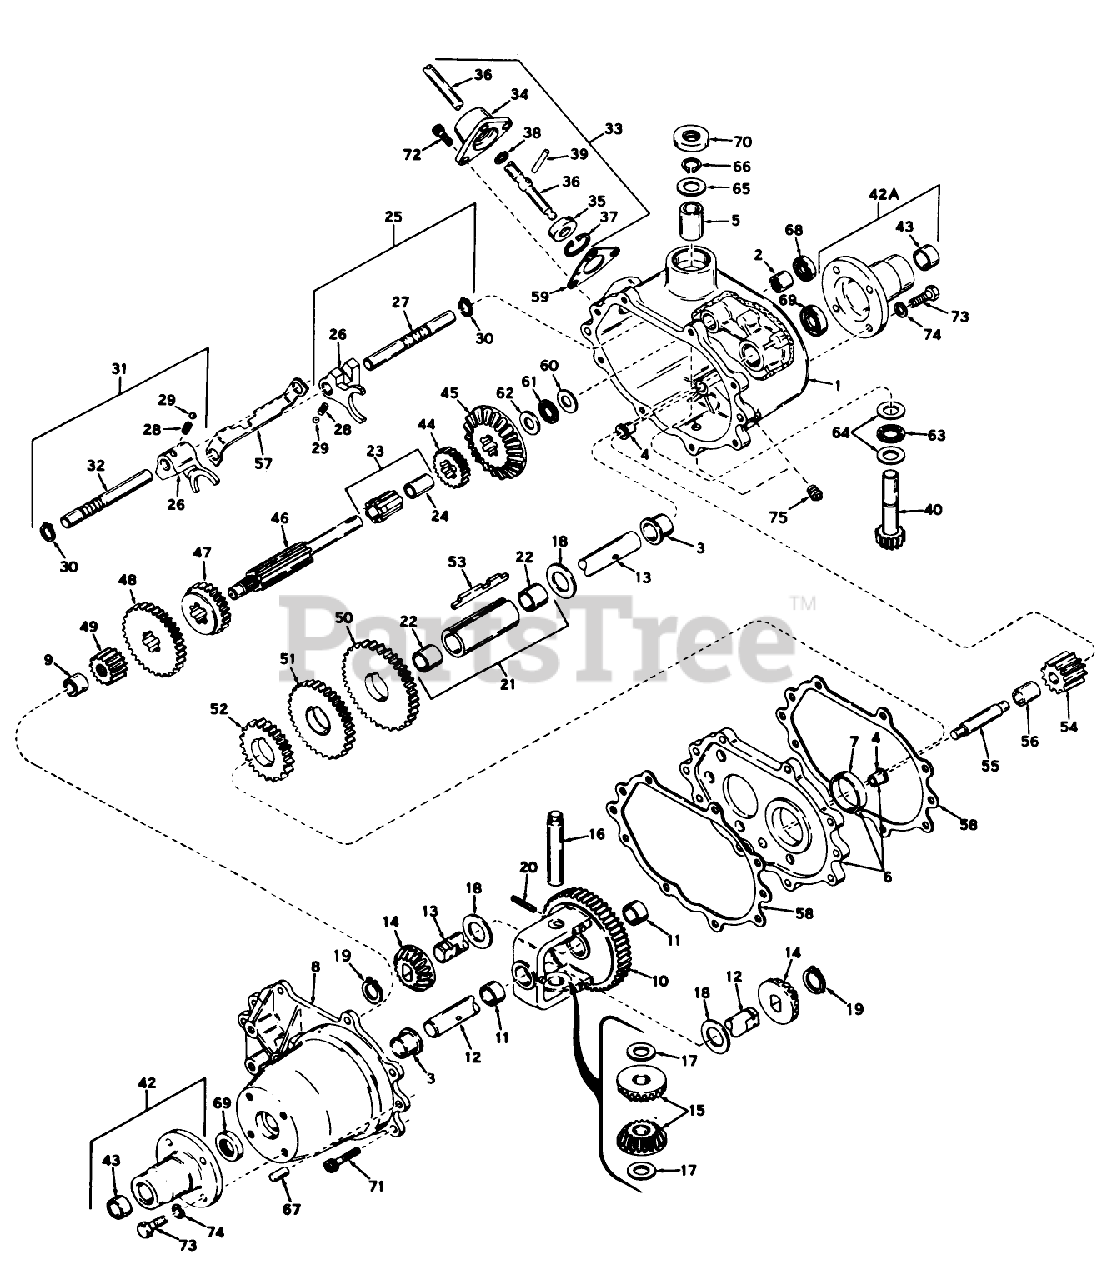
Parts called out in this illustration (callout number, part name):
1	Transaxle Case Assy (Incl. Nos. 2 thru 5)
2	Needle Bearing
3	Bronze Bearing
4	Bronze Bearing
5	Bronze Bearing
6	Plate Assy., Center (Incl. Nos. 4 7)
7	Bronze Bearing
8	Cover Assy., Transaxle (Incl.Nos. 3 9)
9	Needle Bearing
10	Gear Assy., Differential (Incl. No. 11)
11	Bushing
12	Left Hand Axle
13	Right Hand Axle
14	Bevel Gear
15	Gear Pinion
16	Drive Pin
17	Thrust Washer
18	Washer
19	Snap Ring
20	Roll Pin
21	Countershaft Sleeve Assy (Incl. No. 22)
22	Bronze Bearing
23	Idler Shaft Assy (Incl. No. 24)
24	Bronze Bearing
25	Shift Rod Assy (1st and Rev.)(Incl. Nos. 26 thru 30)
26	Shift Fork
27	Shift Rod
28	Spring
30	Ring-Snap
31	Shift Rod Assy (2nd 3rd)(Incl. No. 26, 28, 29, 30, and 32)
32	Shift Rod
33	Shift Lever and Housing Assy (Incl. Nos. 34 thru 39)
34	Shift Lever Housing
35	Keeper-Shift Lever
36	Shift Lever
37	Ring-Snap
38	O Ring
39	Roll Pin
40	Input Shaft
41	Input Pinion
42	No. 43)
42A	Housing Assy Axle (Incl. No. 43)
43	Bronze Bearing
44	Gear (10 teeth)
45	Bevel Gear (33 teeth)
46	Shifter and Brake Shaft
47	Gear, Shifting (2nd 3rd)
48	Gear, Shifting (1st Rev.)
49	Spur Gear (12 teeth)
50	Countershaft Drive Gear (39 teeth)
51	Gear (34 teeth)
52	Countershaft Gear (25 teeth)
53	Countershaft Key
54	Reverse Idler
55	Reverse Idler Shaft
56	Reverse Idler Spacer
57	Shifter Stop
58	Gasket, Case Cover
59	Shift Lever Housing Gasket
60	Thrust Washer
61	Thrust Bearing
62	Thrust Washer
63	Gasket
64	Bearing
65	Ring-Snap
66	RING-SNAP, EXTERNAL
67	Dowel Pin
68	Oil Seal
69	Oil Seal
70	Oil Seal
71	Socket Hd. Cap Screw
73	SCREW-HH
74	WASHER-LOCK
75	CAP-PIPE
